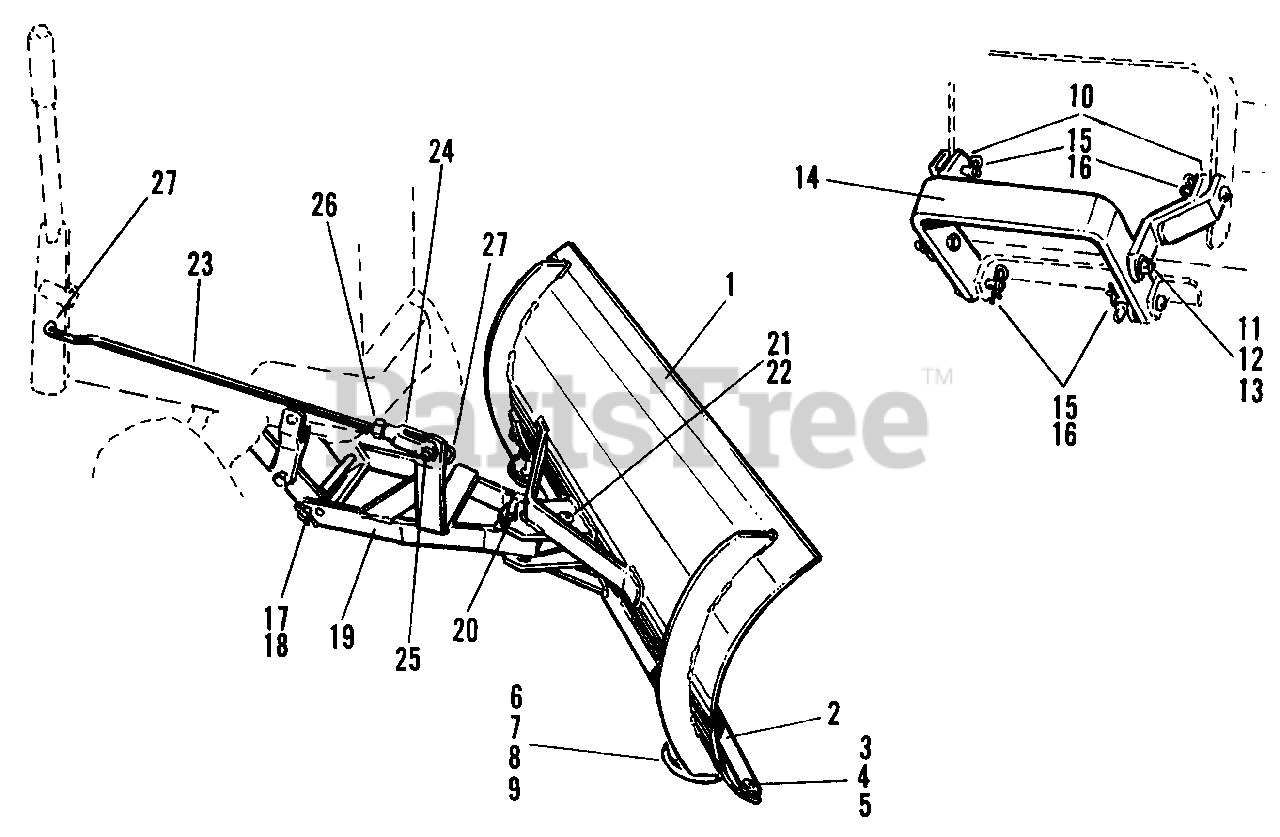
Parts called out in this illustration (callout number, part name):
1	42" Blade Assembly
2	Wear Plate
3	Carriage Bolt, 3/8"-16 x 3/4" lg.
4	Lock Washer, 3/8"
5	Hex Nut, Full, 3/8"-16
6	Shoe Assembly
7	Carriage Bolt, 3/8"-16 x 1" lg.
8	Lock Washer, 3/8"
9	Hex Nut, Full, 3/8"-16
10	Support Arm Assembly
11	Hex Capscrew, 3/8"-16 x 1" lg.
12	Lock Washer, 3/8"
13	Hex Nut, Full, 3/8"-16
14	Push Frame
15	Pin
16	Spring Clip
17	Pivot Rod
18	Spring Clip
19	Push Bar Assembly
22	Spring Clip
24	Adjusting Yoke End
26	Hex Nut, Full, 1/2"-20
27	Spring Clip
